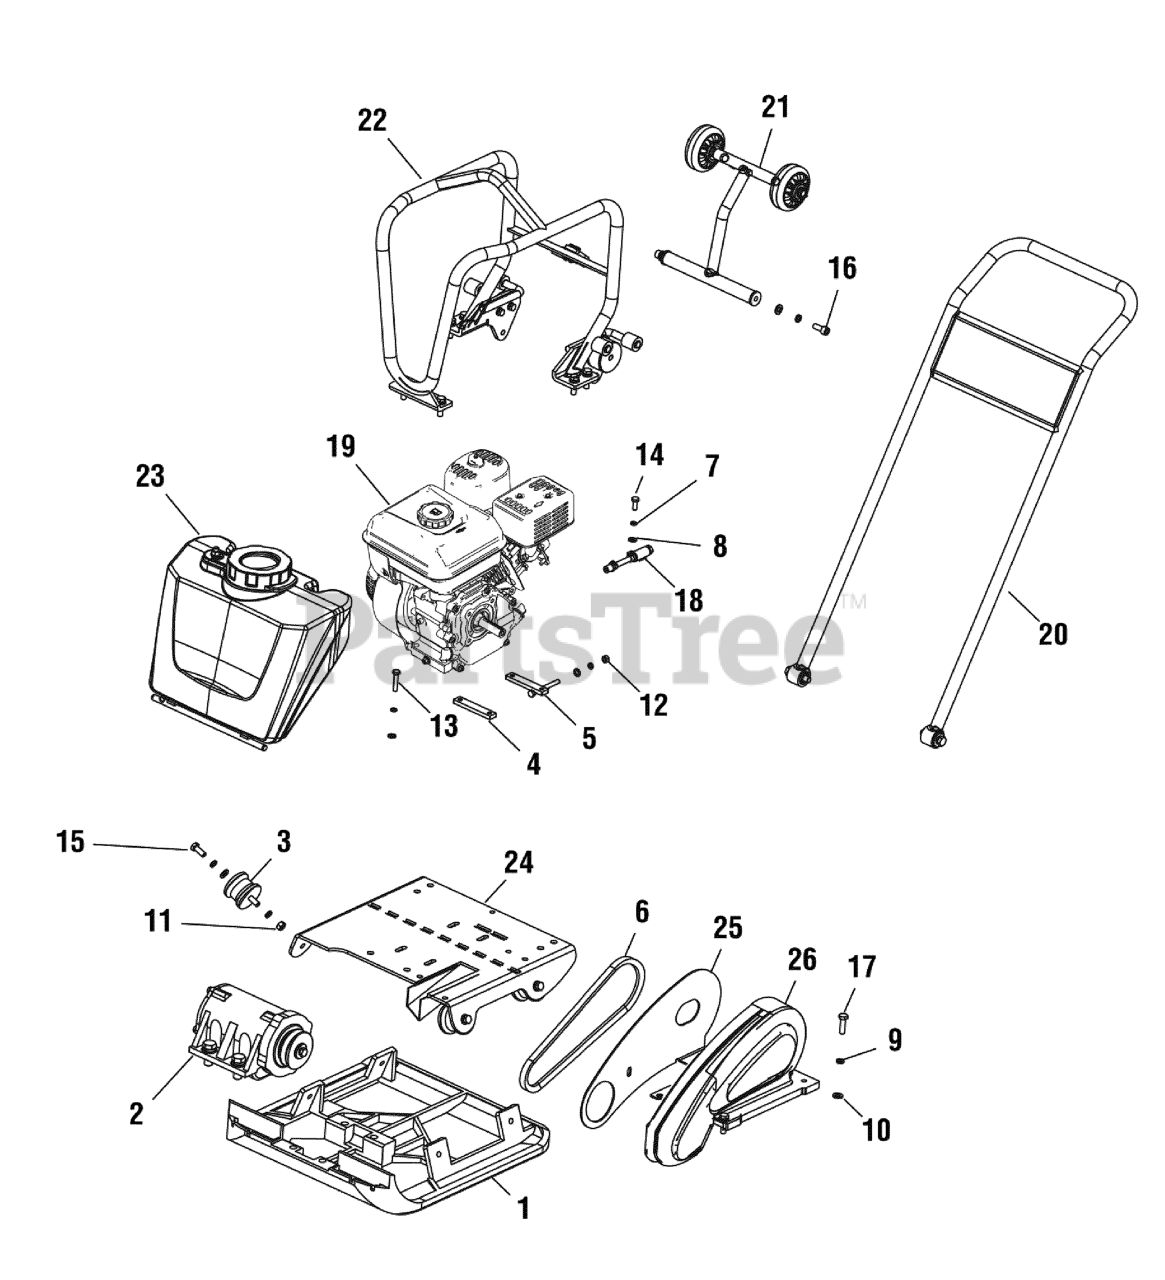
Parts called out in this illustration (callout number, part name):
1	BASE PLATE
2	ECCENTRIC BOX
3	VIBRATION MOUNT, Rubber
4	ENGINE NUT CLAMP
5	ENGINE FIXING PLATE
6	V-BELT, XPA882
7	WASHER, Spring, 8
8	WASHER, Flat, 8
9	WASHER, Spring, 10
10	WASHER, Flat, 10
11	NUT, Hex, M10
12	NUT, Hex, M8
13	BOLT, Hex, M8 x 40
14	BOLT, Hex, M8 x 20
15	BOLT, Hex, M10 x 25
16	SCREW, Socket Head, M10 x 25
17	BOLT, Hex, M10 x 35
18	EXHAUST OIL ASSEMBLY
19	ENGINE ASSEMBLY
20	HANDLE ASSEMBLY
21	ROAD WHEEL FRAME ASSEMBLY
22	TANK GUARD ASSEMBLY
23	WATER TANK ASSEMBLY
24	ENGINE PLATE
25	COVER, Belt, Inner
26	COVER, Belt, Outer
